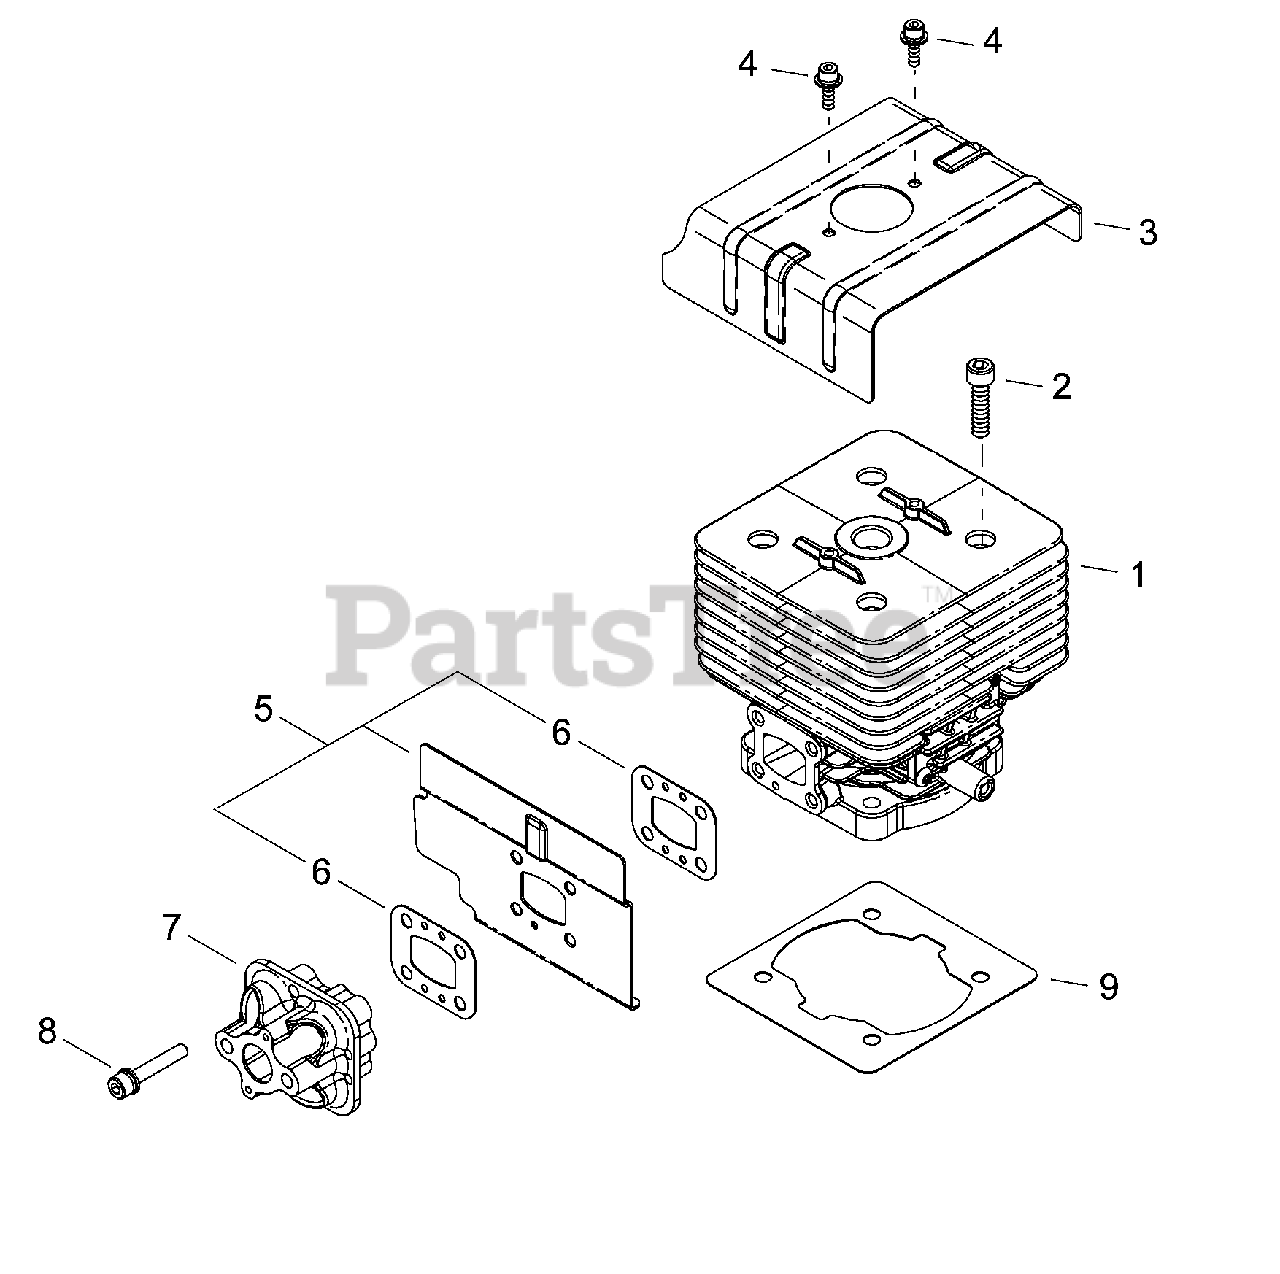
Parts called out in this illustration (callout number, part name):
1	CYLINDER ASSY
2	BOLT 6×25
3	COVER, CYLINDER
4	BOLT M4×12
5	SHIELD ASSY, INTAKE HEAT
6	GASKET, INTAKE
7	INSULATOR, INTAKE
8	BOLT SS M5×30
9	GASKET, CYLINDER
